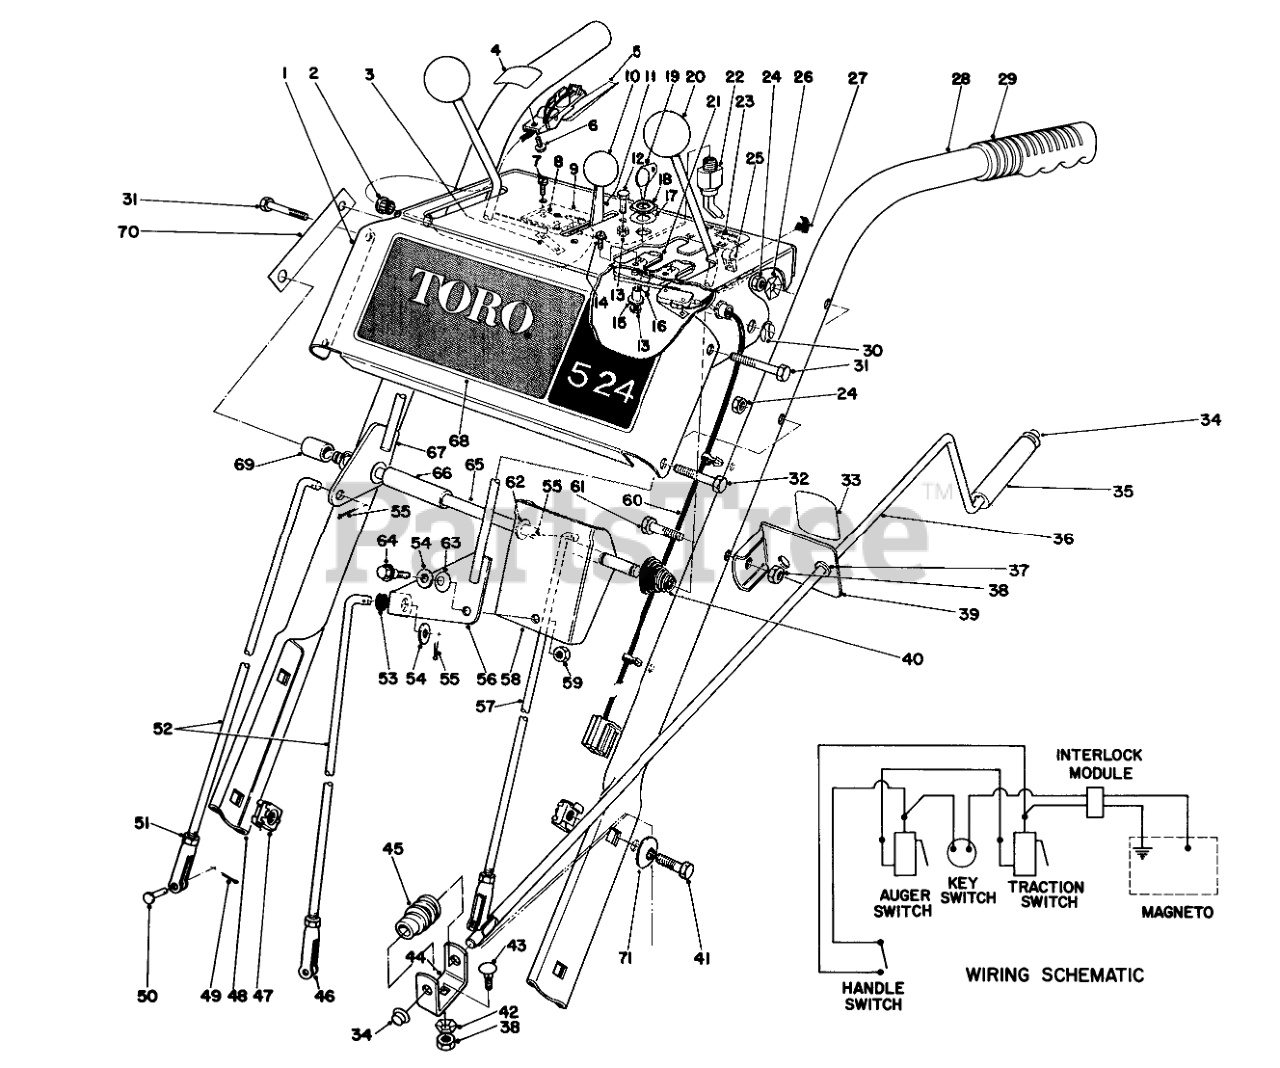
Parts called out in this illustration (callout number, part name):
1	ESCUTCHEON PLT B
2	BUSHING NYLON
3	NUT-SPEED
4	INTERLOCK DECAL
5	INTERLOCK HDLE SWITCH
6	SCREW
7	SCREW-SPH
8	SWITCH-MICRO
9	SWITCH MTG PAD
10	CONTROL KNOB
11	THROTTLE CONTROL
12	HEX HEAD SEMS 10-24X1/2
13	NUT-LOCK, NI
14	SCREW-SRH
15	INTERLOCK SPACER
16	INTERLOCK SPRING
17	WASHER-TOOTH, INTERNAL
18	NUT-HH
19	Key
21	Slide Interlock
22	On-Off Switch (Incl. Ref. #17 & 18)
23	INSTR DECAL
24	NUT-LOCK, CONE
25	WIRE CLAMP
26	Washer
27	Mounting Stud
28	LEFT HANDLE
29	Grip Handle
30	RING-CLIP
31	SCREW-HH
32	SCREW-HH
33	CHUTE DECAL
34	RETAINER-PUSH ON
35	GRIP-CONTROL, CHUTE
36	CHUTE CONTROL ROD
37	Bushing
38	NUT-LOCK, NI
39	Chute Control Rod Mounting (Incl. Ref. #33 & 37)
40	CONICAL SPRING
41	SCREW-HH
42	WASHER-LOCK
43	BOLT-CARR
44	BRACKET-WORM
45	GEAR-WORM, CHUTE
46	CLEVIS
47	Retained Nut
48	HANDLE RIGHT
49	PIN-COTTER
50	PIN-CLEVIS
51	NUT-HJ
52	SPEED SELECTOR ROD
53	GROMMET-RUBBER
54	WASHER-FLAT
55	PIN-COTTER
56	SHIFT LEVER WA
57	TRACTION CONTROL ROD
58	SHIFT BRACKET
59	NUT-LOCK, CONE
60	WIRE HARNESS INTERLOC
61	SCREW-HH
62	WASHER-FLAT
63	7/16 SPRING WASHER
64	SHOULDER SCREW
65	PIVOT ROD
66	SHIFT LEVER SPACER
67	LEVER WA
68	ESCUTCHEON DECAL
69	AUGER LEVER SPACER
70	ESCUTCHEON SUPT STRAP
71	WASHER-SPRING
